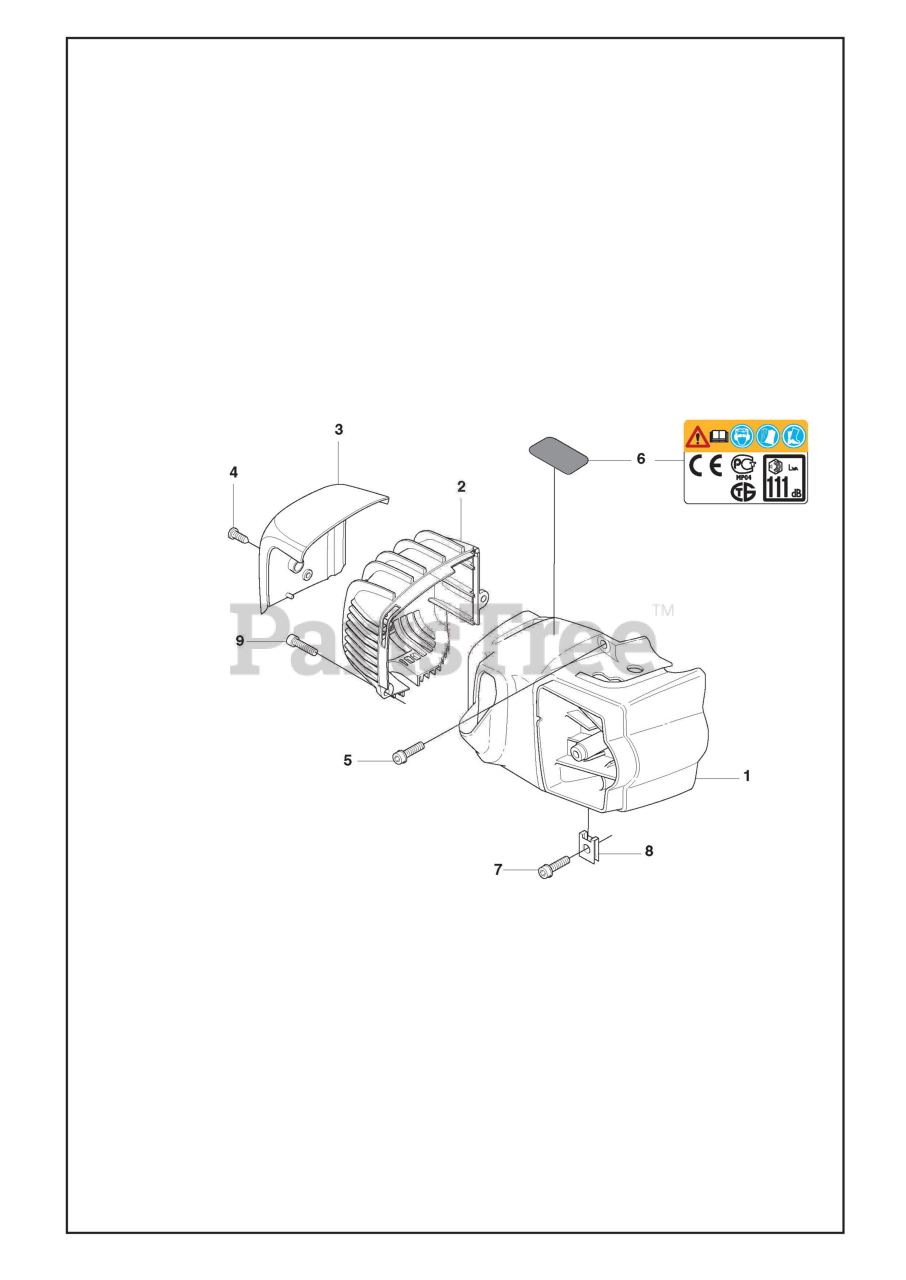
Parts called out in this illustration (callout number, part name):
1	CYLINDER COVER CAPTIV
2	HEAT PROTECTOR
3	MUFFLER SHIELD
6	LABEL WARNING CE
9	SCREW W/ LOCKING FLUID
